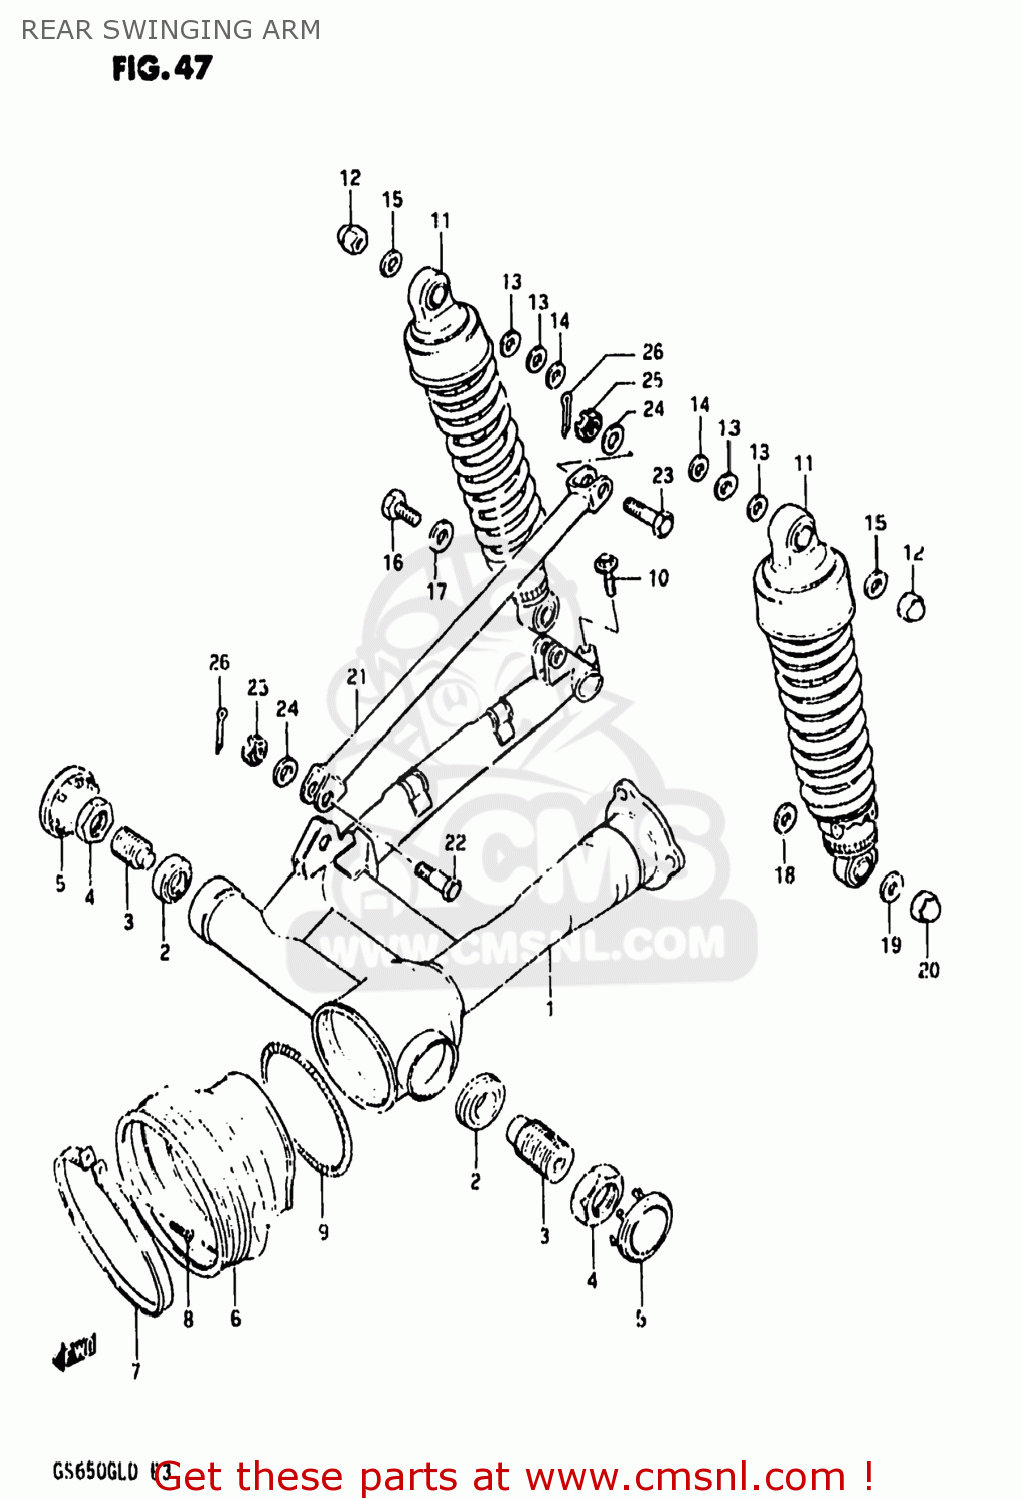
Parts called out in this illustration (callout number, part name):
1	SWING ARM ASSEMBLY,REAR
2	BEARING(15X35X11.75)
3	BOLT,REAR SWING ARM PIVOT
4	NUT (22MM)
5	CAP,REAR SWING ARM PIVOT
6	BOOT,PROPELLER SHAFT
7	CLAMP
8	SCREW 4X25
9	SPRING,PROPELLER SHAFT
10	BOLT
11	ABSORBER ASSEMBLY,REAR SHOCK
12	NUT
13	WASHER
14	WASHER (12.5X24X3.2)
15	WASHER
16	BOLT 12X33
17	WASHER (12.5X24X1.6)
18	WASHER
19	WASHER
20	NUT, LOWER LH
21	TORQUE LINK,REAR
22	BOLT
23	BOLT(10X39)
24	WASHER
25	NUT
26	PIN 20X20
